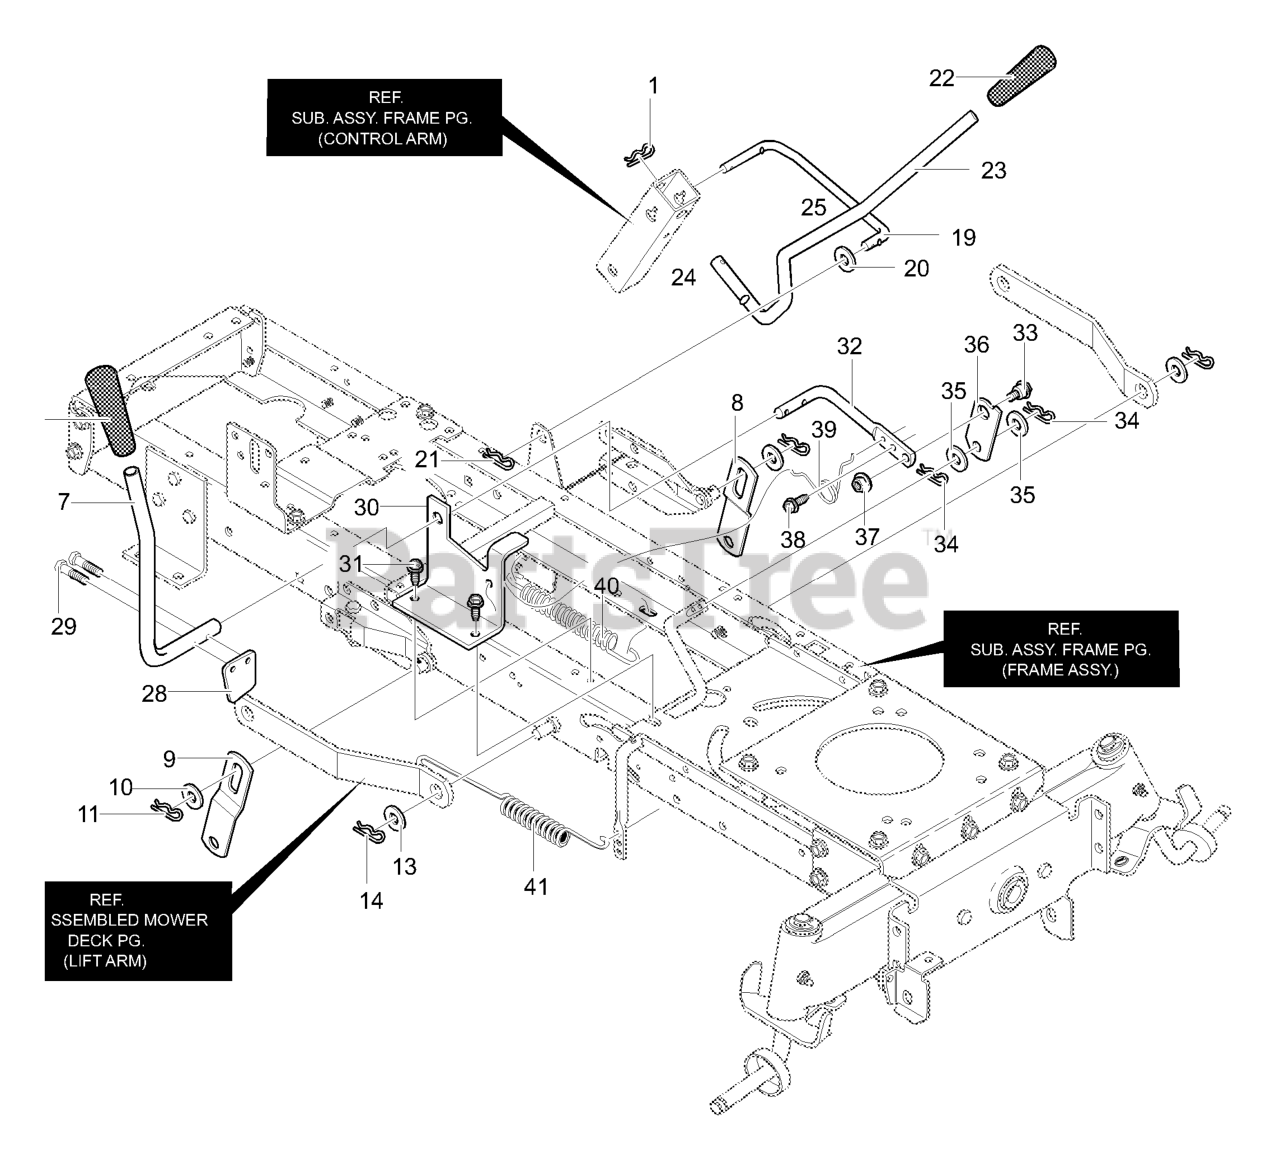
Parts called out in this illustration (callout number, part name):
1	Hair Pin
8	Link, Lift LH
9	Link, Lift RH
10	Flat washer
11	Hair Pin
13	Flat washer
14	Hair Pin
19	Link, Lift Handle
20	Flat washer
21	Hair Pin
22	Grip
23	Handle, Lift
24	Washer, Flat
25	Torsion Spring
26	Grip
27	PTO Handle
28	Paddle Switch
29	Screw, Thd Form
30	Bracket, PTO
31	Screw, 5/16-18 x 0.50
32	Lever, PTO
33	Bolt, Shoulder 3/8-16
34	Hair Pin
35	Washer, Flat
36	Link PTO
37	Nut, 3/8-16
38	Screw, 5/16-18 x 0.75
39	Torsion Spring
41	Spring, Extension
